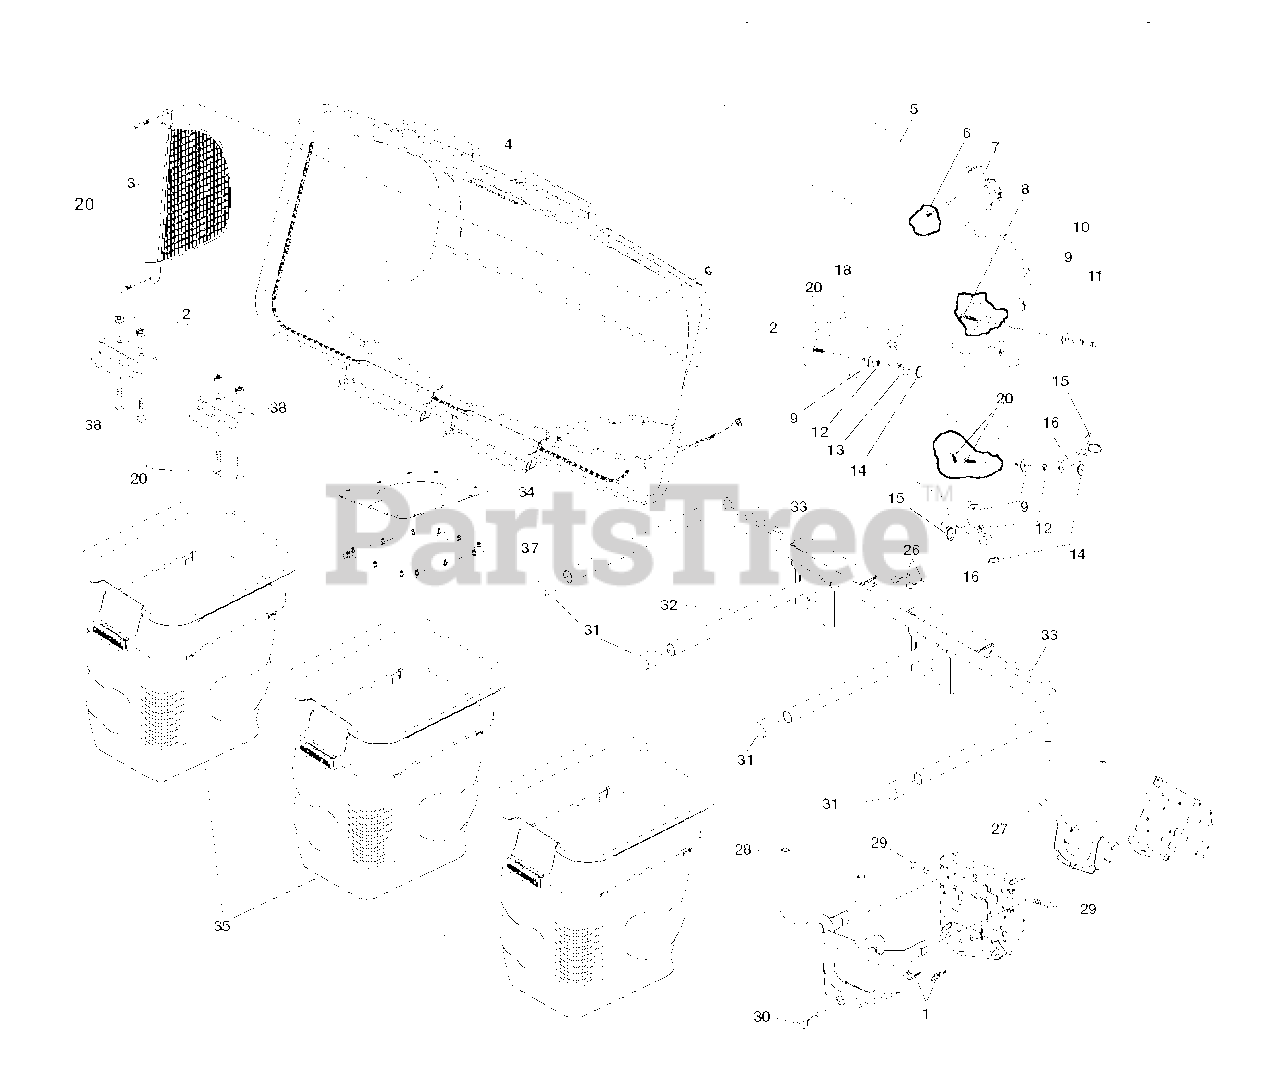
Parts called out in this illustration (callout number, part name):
1	ADAPTER.LT.3-BIN.QA.TEX
3	SCREEN.COVER.BAGGER
4	COVER.ASM.3BIN.GENERIC.
5	CHUTE.BAGGER.UPPER.48
7	INDICATOR ASM BAG
8	SCREW
11	NUT
12	LOCKWASHER (3 2)
13	LATCH.HOOD.
14	WELDNUT
15	HOOK LATCH
16	RUBBER LATCH
18	CHUTE.BAGGER.LOWER.48"
20	SCREW
26	Retainer Spring
27	BAGGER.ASM.SUPPORT.GT.TEX.BLAC
29	SHOULDER BOLT, SELF-TAP
30	SPRING.RETAINER.YELLOW.ZINC
31	PLUG, TUBING END
32	BAGGER.ASM.FRAME.3BIN.BLACK
33	BAGGER.HINGE.PIN
34	SEAL.BAGGER.TOP.3-BIN.BLK
35	CONTAINER BAG, SOFT
37	GASKET.COVER.BAGGER
38	LATCH CER38
